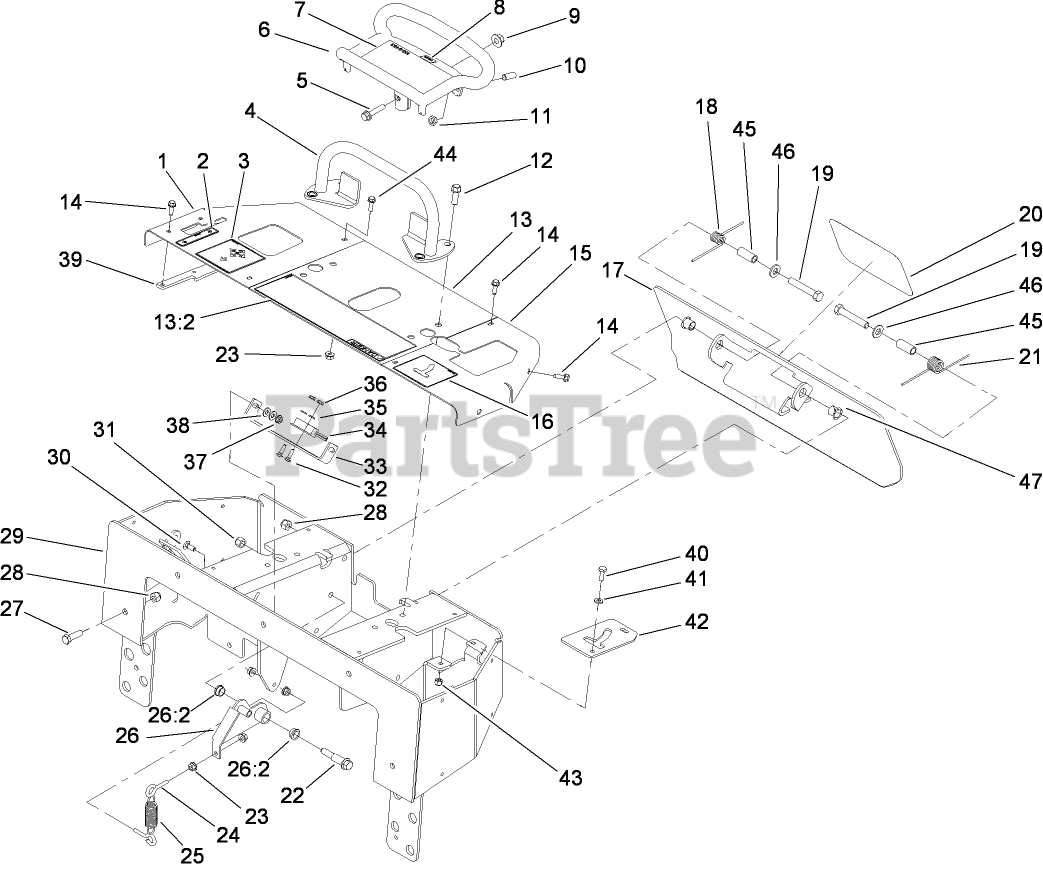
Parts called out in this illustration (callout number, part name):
1	PANEL-RH
2	DECAL-BRAKE
3	DECAL-LOADER
4	BAR-REFERENCE
5	SCREW-HHF
6	HANDLE-CONTROL
7	DECAL-TRACTION
8	DECAL
9	NUT-FLANGE
10	SCREW-SET
11	NUT-JAM
12	SCREW-TAPTITE
13	CENTER PANEL ASM
13:2	DECAL-DANGER
14	SCREW-HWH
15	PANEL-LH
16	DECAL-AUXILIARY
17	PLATE-REVERSE
18	SPRING-TORSION, LH
19	SCREW-HH
21	SPRING-TORSION, RH
22	BOLT-SHOULDER
23	NUT-HHF
24	BOLT-EYE
25	SPRING-EXTENSION
26	NEUTRAL CENTERING LEVER ASM
26:2	BUSHING-FLANGE
27	SCREW-HH
28	NUT-LOCK, NI
29	PANEL-CONTROL
30	BOLT-CARR
31	NUT-LOCK
32	SCREW-CARR
33	PLATE-SWITCH
34	SWITCH-PROXIMITY
35	WASHER-FLAT
36	NUT-KEPS
37	NUT-KEPS
38	WASHER-FLAT
39	PLATE-LOCKING, BRAKE
40	SCREW-HH
41	WASHER-FLAT
42	PLATE-STOP
43	NUT-LOCK, NI
44	SCREW-HWH
45	SPACER-SPRING
46	WASHER-FLAT
47	BUSHING-NYLINER
